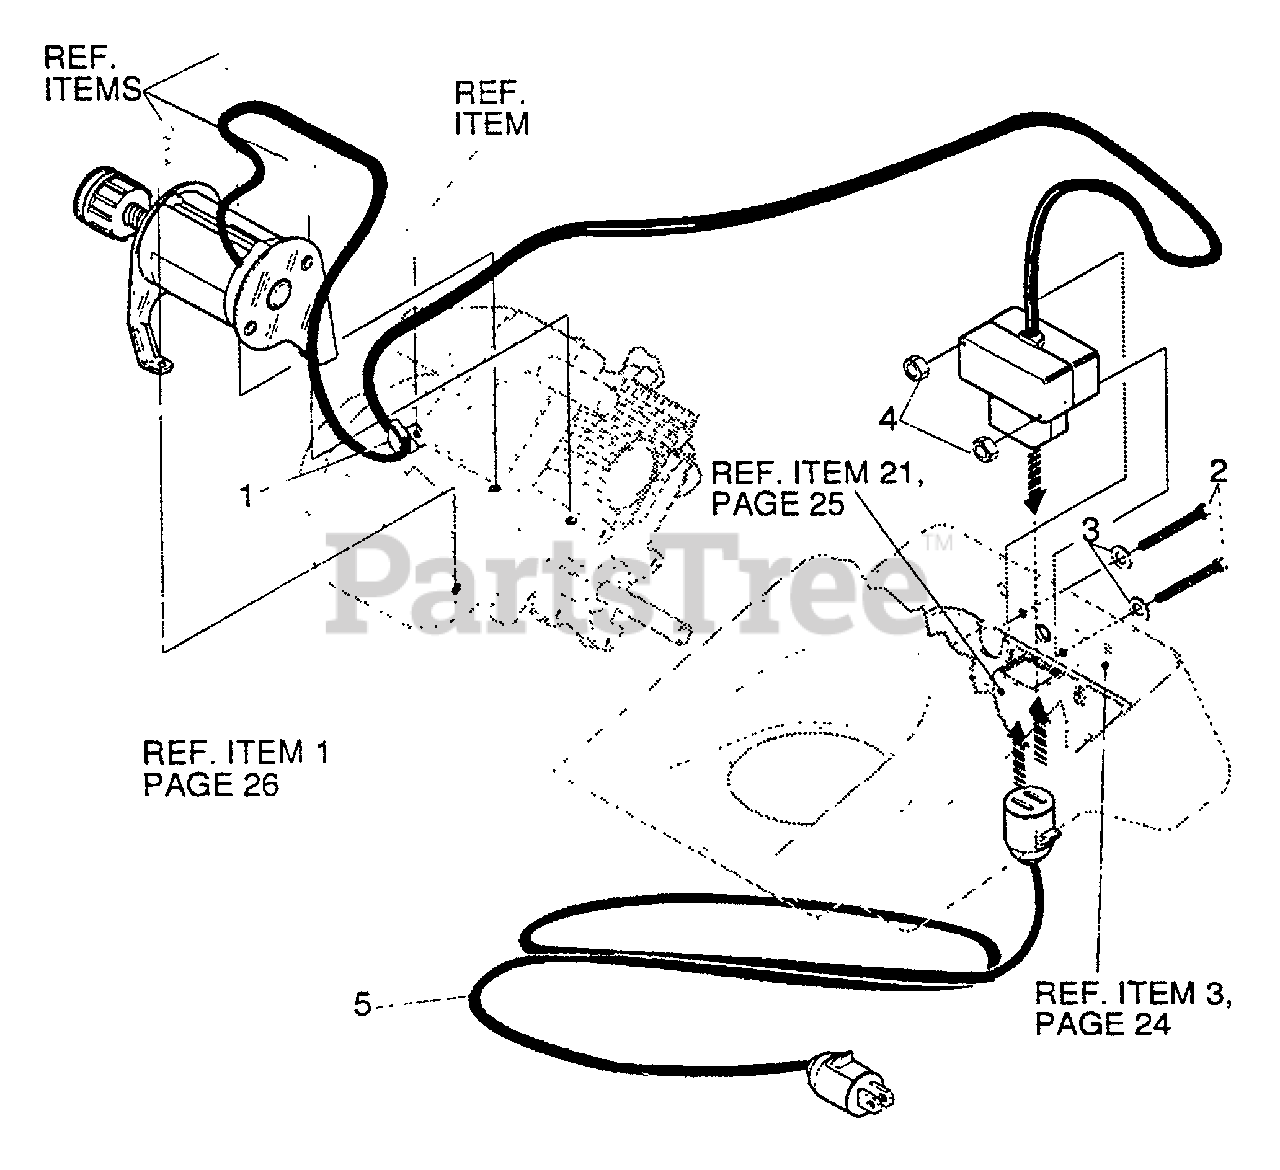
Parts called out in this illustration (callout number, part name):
1	RETAINER, WIRE
2	SCREW - 8-32×3.00"
3	WASHER - 0.188×0.38×0.040"
4	NUT - 8-32 -- KEPS
5	CORD, EXTENSION 10 FEET
